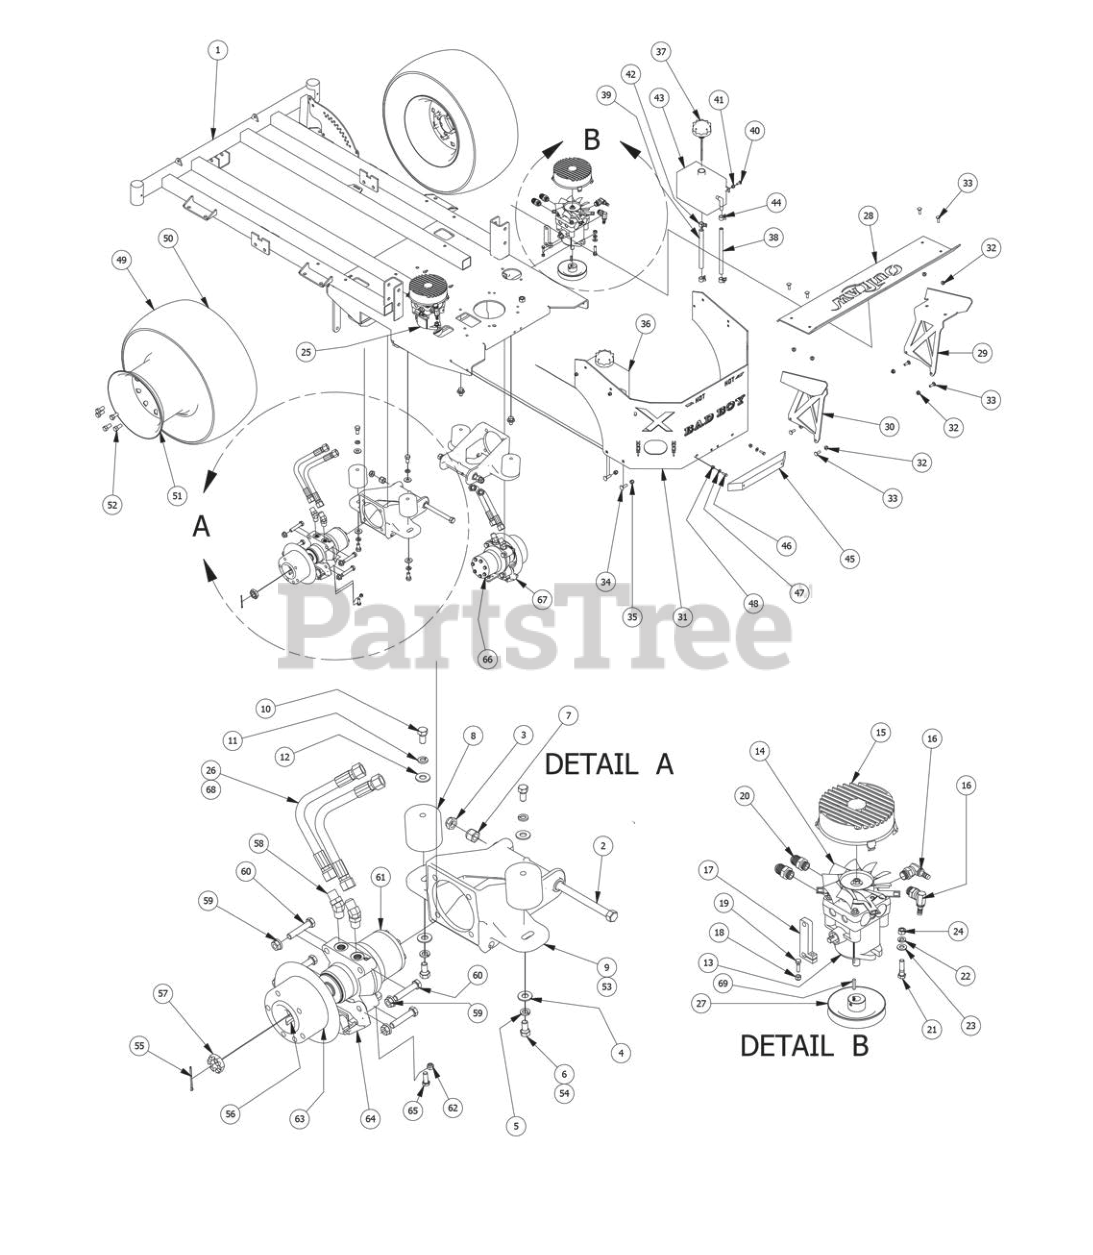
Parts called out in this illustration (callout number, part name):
1	2012 Suspension Outlaw
2	5/8"x10" Hex Bolt (Grade8)
3	5/8" Nylock (1/2 Jam)
4	1/2" Washer (Grade 8)
5	1/2" Lock Washer
6	1/2" x 1" Hex Bolt
7	5/8 Std NC Nylock Nut
8	Vibration Mount-Green Dot
9	60" Suspension Kit Wheel Motor
10	1/2" x 1" Hex Bolt
11	1/2" Lock Washer
12	1/2" Washer (Grade 8)
13	Left Pump 12cc
14	Hydraulic Fan
15	Fan Guard 6" Fits wheel Motor Pumps
16	3/8" X 9/16"-18 ORB Male Fitting (S,A-2 P-4)
18	1/4" Nylock Nut
19	1/4-20 x 1 GR 5 hex bolt zinc
20	Hydraulic Pump Fitting 6400-10
21	3/8" x 1 1/2" Hex Bolt
22	3/8" Lock Washer
23	3/8" Flat Washer
24	3/8" Hex Nut
25	Right Pump 12cc
26	18" hose Assembly W/forged 45 Degrees
27	5" Pump Pulley
28	Outlaw Spoiler Plate
29	Outlaw Susp Spoiler Bracket (Right)
30	Outlaw Susp Spoiler Bracket (Left)
31	Outlaw Rear Cover Plate Susp Frame
32	5/16" Flange Nut Zinc W/Serrations
33	5/16" x 1" Carriage Bolt
34	3/8" x 1 1/4" Carriage Bolt
35	3/8 Nylock Nut
36	Outlaw Hydraulic Tank Left
37	Hydraulic Tank Cap W/Dipstick
38	3/8 clear hose price per foot
39	1/2 Clear Braded Hose Priced/Foot
40	1/4" x 3/4" Carriage Bolt
41	1/4-20 Nylon Insert flange Nut
42	1/2 Hose Clamp
43	Outlaw Hydraulic Tank Right
44	3/8 hose clamp
45	14" Rubber Bumper
46	1/4-20 x 1-1/4 GR 5 Hex Bolt
47	1/4" Flat Washer
48	1/4-20 Nylon Insert flange Nut
49	24 x 12.00-10 Tire and Wheel assembly
50	24 x 12.00-10 outlaw Tire
51	10" Wheel For Outlaw
52	1/2-20 x 1-1/2 Lug Bolts Zinc
53	72" Suspension Kit Wheel Motor
54	1/2-13 x 1/1/4 Hex Bolt Only on 60" Suspension kit wheel Motor
55	1/8x2-1/4 cotter pin Zinc
56	Woodruff Key
57	1" Castle Nut for Wheel Motor
58	45 Degree Fitting 31704-10-10
59	1/2" Flange Nut
60	1/2" x 2 1/2" Hex Bolt
61	15cc Parker Wheel Motor- Left
62	5/16-18 Nylock Insert Locknut
63	Brake Disk
64	XP/AOS Left Brake Caliper
65	3/8" x 1" Hex Bolt
66	15cc Parker Wheel Motor- Right
67	XP/AOS Right Brake Caliper
68	18" Hydraulic Hose Only
69	3/16 x 1 Square Key
